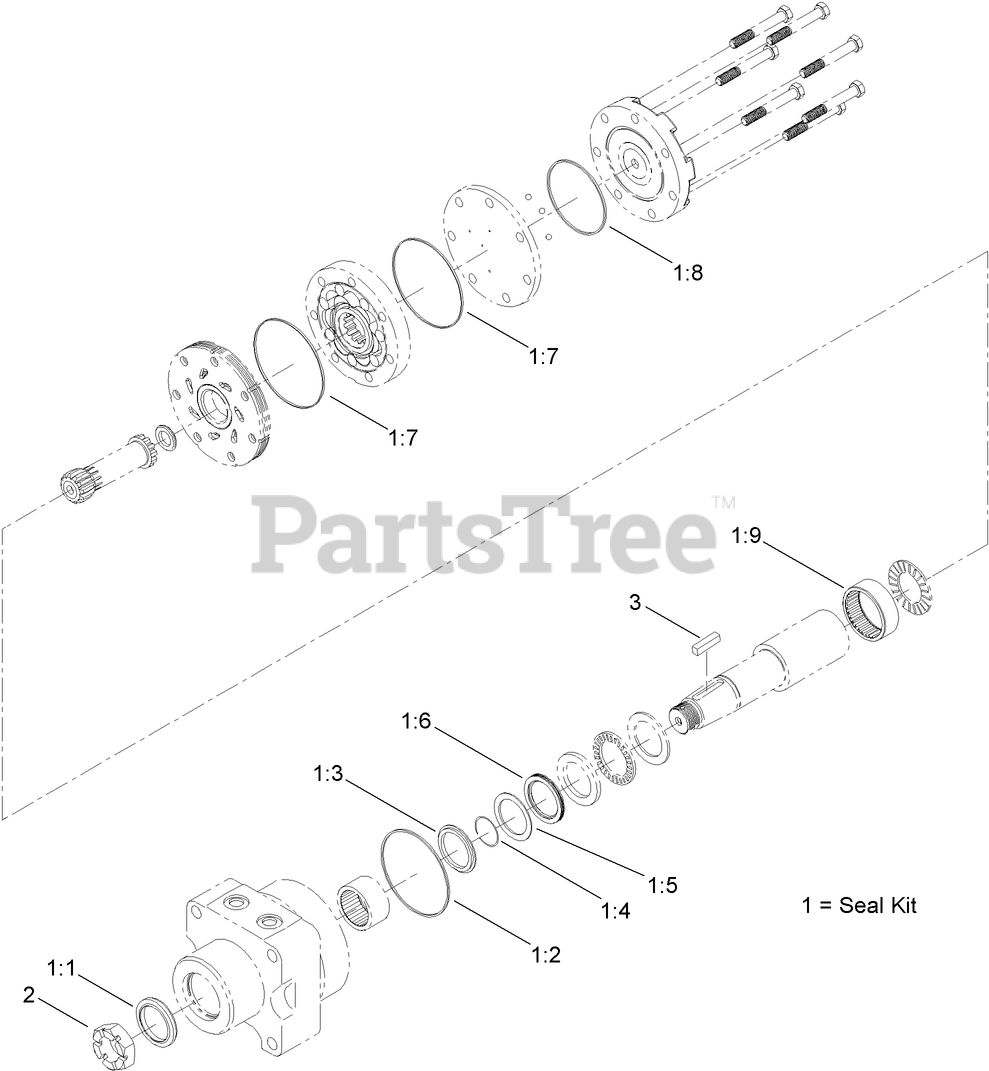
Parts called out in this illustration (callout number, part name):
1	SEAL KIT
1:1	SEAL-DUST
1:2	SEAL-HOUSING
1:3	RING-BACK UP, METAL
1:4	SHIM-BACK UP
1:5	Seal-Back Up
1:6	SEAL-Shaft
1:7	SEAL-BODY
1:8	SEAL-ENDCOVER
1:9	BEARING-HOUSING, REAR
2	NUT-SHAFT
3	KEY-SHAFT
